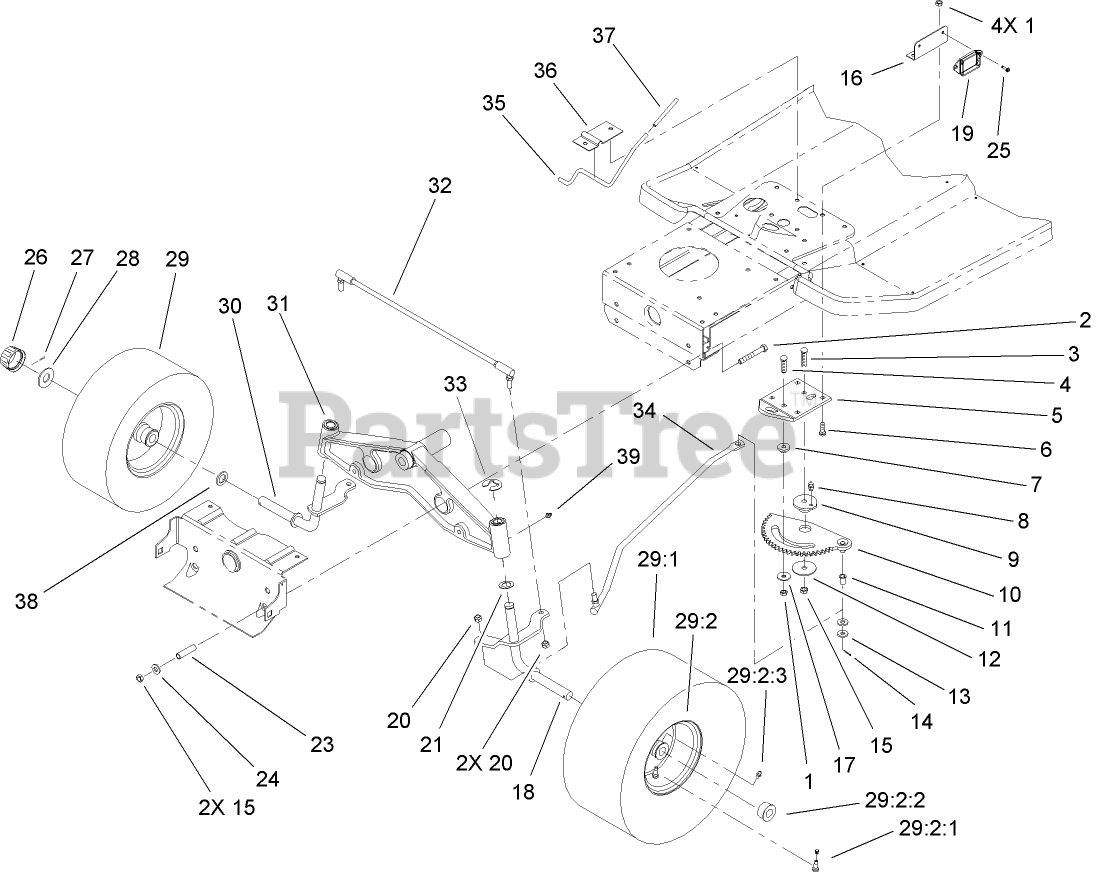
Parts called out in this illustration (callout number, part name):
1	NUT-LOCK, NI
2	SCREW-HH
3	SCREW-CARR
4	SCREW-CARR
5	BRACKET-RACK, STEERING
6	BOLT-CARR
7	SPACER-RACK, STEERING
8	FITTING-GREASE
9	BUSHING-ECCENTRIC
10	RACK-STEERING
11	BUSHING-FLANGED, NYLON
12	WASHER-BEARING
13	WASHER-FLAT
14	PIN-COTTER
15	NUT-LOCK, NI
16	BRACKET-MODULE
17	WASHER-PIVOT
18	LH SPINDLE ASM (BLACK)
19	MODULE-CLUTCH
20	NUT-HEX
21	WASHER-THRUST
23	SPACER
24	WASHER-FLAT
25	SCREW-HWH
26	CAP-HUB
27	PIN-COTTER
28	WASHER-PLAIN
29	Loose Parts Package
29:2:2	BEARING-WHEEL
29:2:3	FITTING-GREASE
30	RH SPINDLE ASM
31	AXLE-FRONT
32	TIE ROD ASM
33	E-RING
34	LINK-DRAG
35	ROD-BRAKE, PARKING
36	BRACKET-PARKING BRAKE
37	GRIP-BRAKE, PARKING
38	WASHER-THRUST
39	FITTING-GREASE
